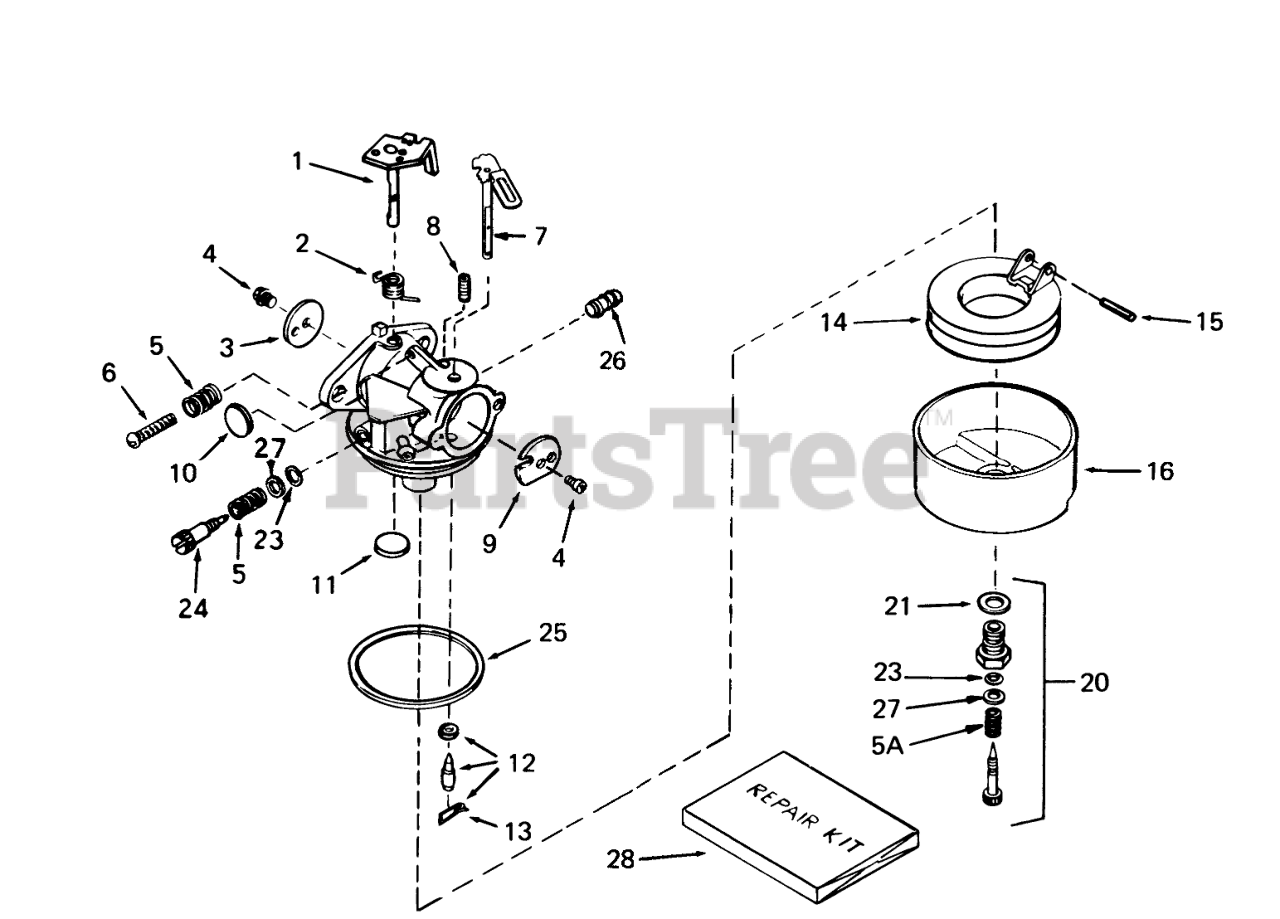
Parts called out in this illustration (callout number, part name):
1	Shaft/Lever-Throttle
2	Spring-Return, Throttle
3	Shutter-Throttle
4	Screw-Shutter
5	Spring-Tension
6	Screw-Throttle Crack Screw / Idle Speed
7	Choke Shaft and Lever ASM
8	Spring-Positioning, Choke
9	Shutter-Choke
10	Plug-Welch, Idle Mixture Well
11	Plug-Welch, Atmospheric Vent
12	Inlet Needle, Seat & Clip Assy. (Incl. Ref. #13)
13	Clip-Spring
14	Float
15	Shaft-Float
16	Bowl-Float (no drain)
20	Adjustment Screw Assy. (Incl. Ref. #5A, 21, 23 & 27)
21	Washer-Bowl Nut
23	"O"Ring
24	Screw Main Adjustment
25	O Ring-Bowl, Float
26	Fitting-Fuel
28	Repair Kit
